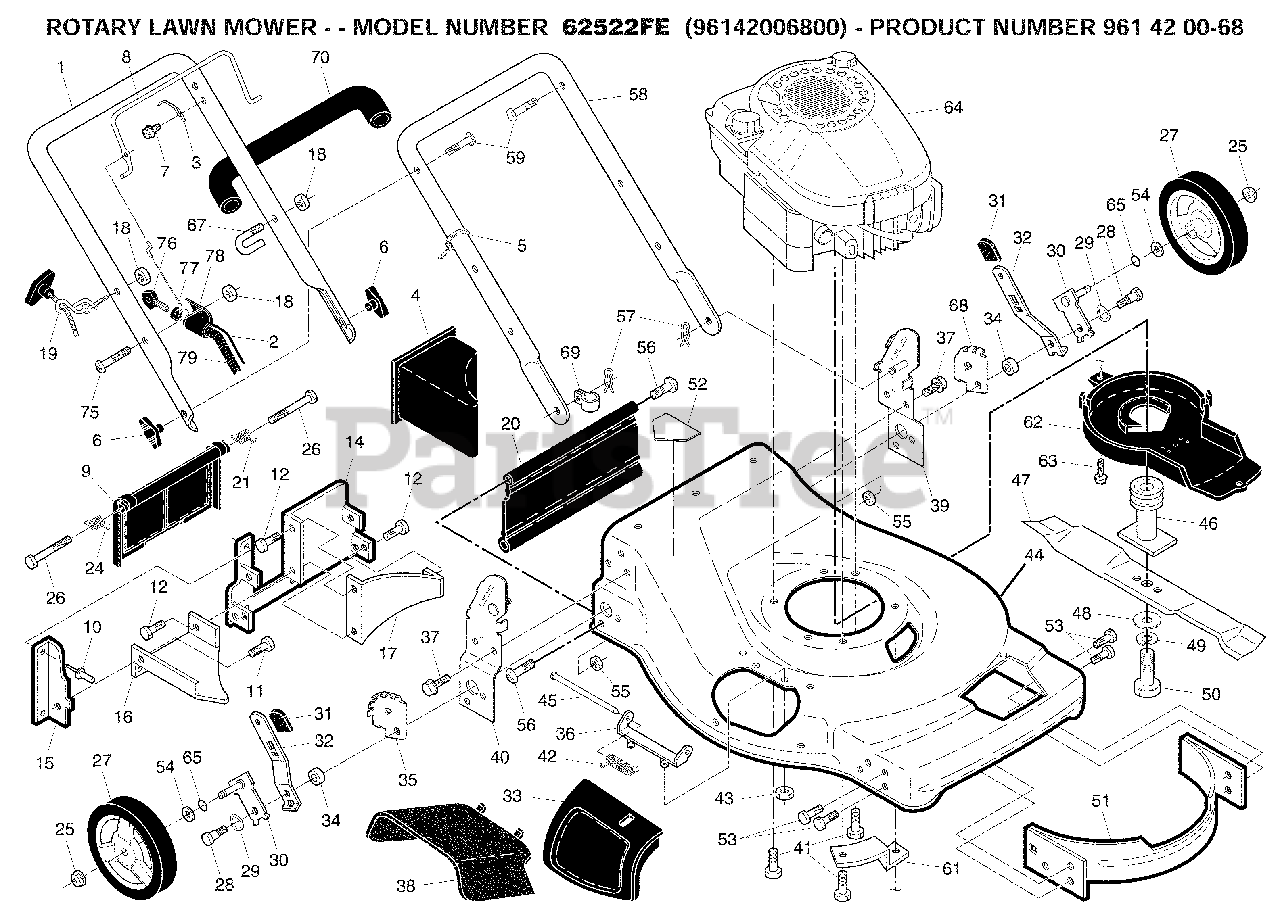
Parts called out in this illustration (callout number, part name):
1	Upper Handle
2	Cable, Operator Presence
3	Bracket, Upstop
4	Mulcher Plug
5	Wire Tie
6	Handle Knob
8	Control Bar
9	Rear Door Assembly
11	Screw, Self-Tapping #10-24 x 5/8
12	Screw, Hex Hex Head, Sems 1/4-20 x 1/2
14	Back Plate
15	Side Baffle
16	Discharge Baffle
17	Rear Baffle
18	Keps Locknut 1/4-20
19	Rope Guide
20	Rear Skirt
21	Spring, Rear Door, LH
24	Spring, Rear Door, RH
25	Nut, Hex, Flanged
26	Bolt, Rear Door
27	Wheel & Tire Assembly, Rear
28	Bolt, Shoulder 3/8-16 x 1
29	Washer, Belleville
30	Axle Arm Assembly
31	Selector Knob
32	Selector Spring
33	Mulcher Door
35	Wheel Adjusting Bracket, RH
36	Hinge Bracket Assembly
37	Screw, Sems, Thread Cutting 5/16-18 x 3/4
38	Discharge Deflector
39	Handle Bracket Assembly, LH
40	Handle Bracket Assembly, RH
41	Screw, Hex Head, Threaded, Rolled 3/8-16 x 1-1/8
42	Spring, Torsion
43	Nut, Hex, Nylock
44	Kit, Lawn Mower Housing
45	Rod, Hinge
46	Blade Adapter / Pulley
47	Blade, 22"
48	Washer, Hardened
49	Washer, Helical
50	Screw, Machine, Hex Head 3/8-24 x 1-3/8 Grade 8
51	Front Baffle
52	Danger Decal
54	Washer, Flat
55	Nut, Hex
56	Screw, Hinge 1/4-20 x 1-1/4
57	Hairpin Cotter
58	Lower Handle
59	Handle Bolt
61	Bracket Debris Shield
62	Debris Shield
63	Screw, Debris Shield
64	Engine, Briggs & Stratton, Model Number 122L05-1263-F1
67	Clip, Packaging
68	Wheel Adjusting Bracket, LH
69	Clip, Cable
78	Key Start Switch
79	Wiring Harness
